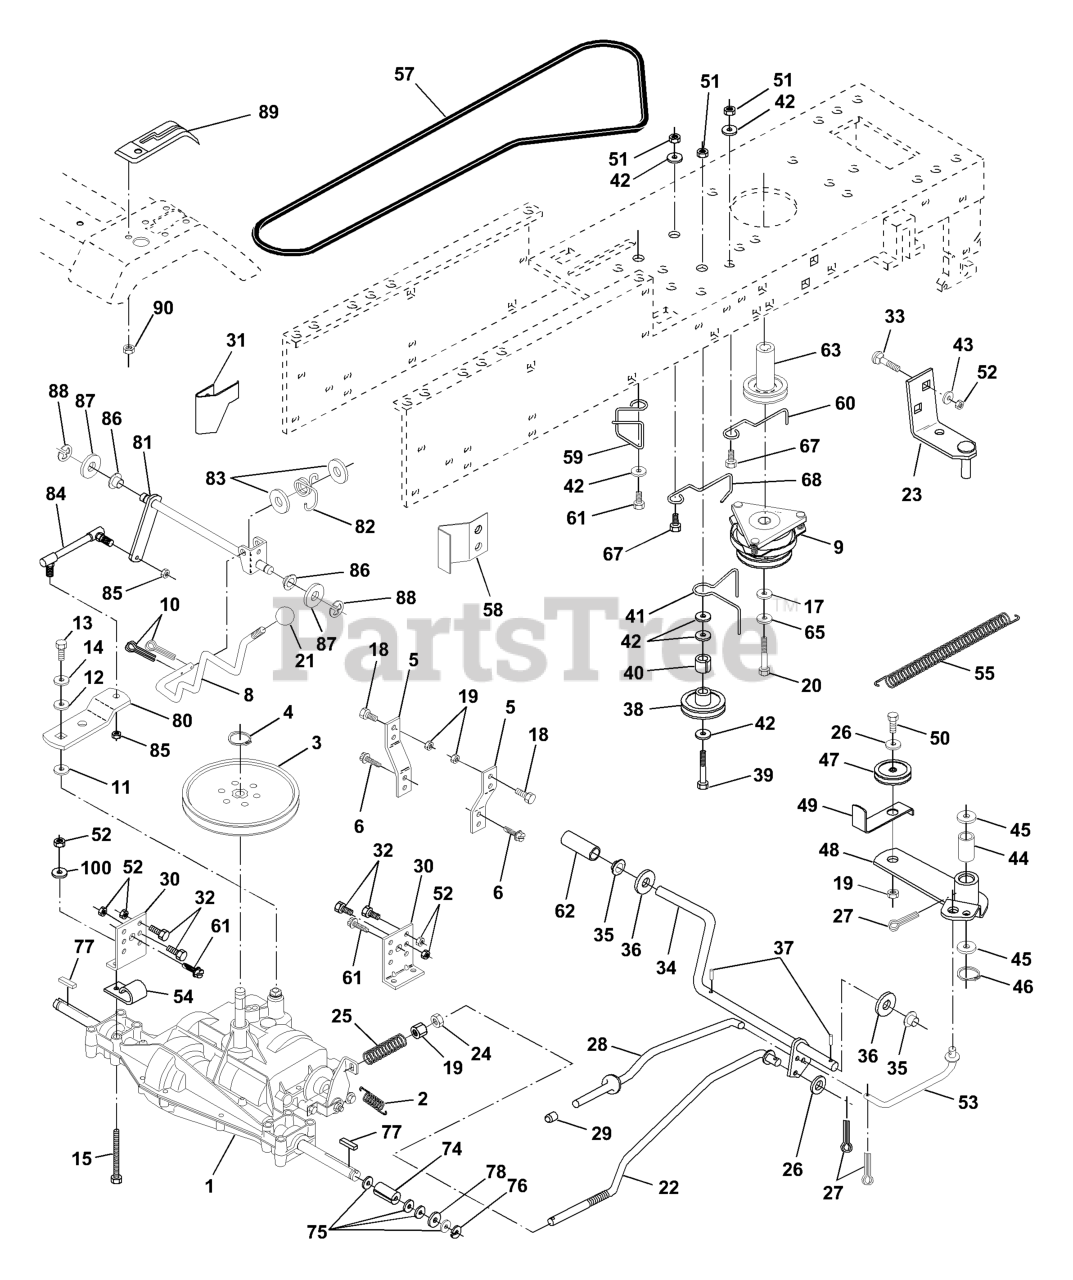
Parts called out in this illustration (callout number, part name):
1	TRANSAXLE
2	SPRING T
3	PULLEY TRANS
4	RETAINING RING LT
5	STRAP TORQUE
6	SCREW.THDROL.5/16-18X3/4.TTY
9	CLUTCH.ELECT.CVX.105 FT/LB.
10	PIN COTTER
11	WASH-SHFT PLT LT
12	Washer 15/32 X 3/4 X 16 Ga
13	BOLT LT
14	LOCKWASHER
15	BOLT HEX
16	NUT.71038.31-18.HEX.NYLOCK
18	BOLT
19	NUT
21	KNOB.DUCKHEAD.1/2
23	BRACKET ASM MTG
24	NUT
25	SPRING ROD LT
26	WASHER
27	COTTER PIN
28	BRAKE PARK ROD
29	PLUNGER CAP
30	BRACKET TRANSAXLE
31	KEEPER BELT LH
32	BOLT
33	RP BOLT 5/16-18 X3/4 ZN/YEL GR
34	SHAFT FOOT PEDAL
35	BEARING.NYLON
36	WASHER LT
37	DRIVE PIN
38	PULLEY.IDLER.FLAT
41	BELT KEEPER LT NLA
42	WASHER
43	WASHER T
44	BEARING LT (2 2)
47	IDLER PULLEY
49	RETAIN BELT
50	BOLT
52	LOCKNUT
53	LINK, CLUTCH LT
54	CLIP T
55	SPRING, RETURN LT
57	V-BELT
59	KEEPER CENTER SPAN
61	SCREW
62	COVER, PEDAL (1 2)
63	PULLEY CLU ELEC
64	BOLT
65	LOCKWASHER
66	KEEPER BELT ENGLH
67	BOLT
70	KEEPER,BLT ENG LT
77	SQUARE KEY
81	SHAFT ASMBLY
82	SPRING,TORSION
83	WASHER
85	NUT 1/4-28
86	BUSHING.STEERING.ROD LTB-WSL
89	CONSOLE SHIFT
90	NUT.PUSH.3/16
100	WASHER M
